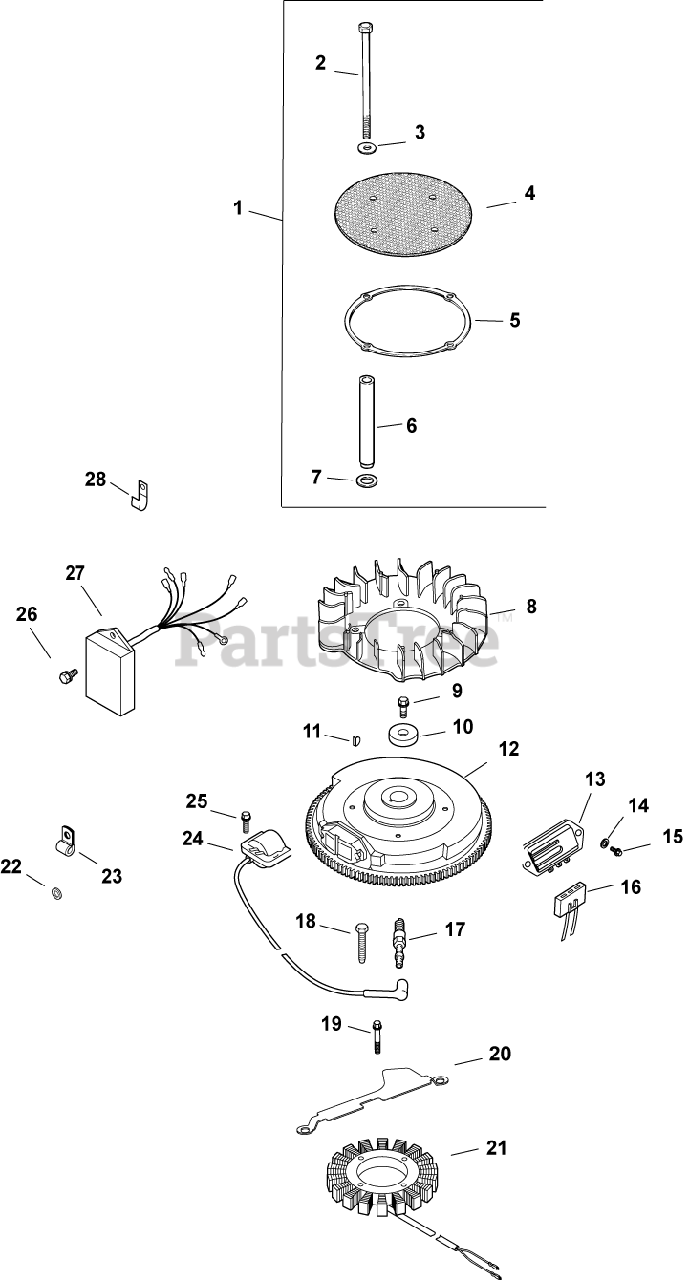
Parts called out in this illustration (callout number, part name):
1	KIT, CHOPPER SCREEN
2	SCREW, CAP M6X1.0X99.5
3	WASHER, FLAT 1/4" (O.D. 5/8")
4	SCREEN, GRASS
5	RING, SUPPORT USE 25 141 08-S
7	WASHER, SPRING 10 MM
8	FAN (DOMED)-USE 24 157 17-S
9	SCREW, FLG M10X1.5X45 - (#25086361S)
10	WASHER, FLAT 13/32"
11	KEY, 3/16" X 5/8"
12	FLYWHEEL, PAINTED-USE 24 025 56-S
13	REG/RECT-15 AMP (KM)-USE 41 403 10-S
14	WASHER, FLAT 3/16"
15	SCREW, PHL HD #11-16X7/8"
16	CONNECTOR, BODY (KM)-USE 25 155 41-S
17	PLUG, SPARK (STD)
18	SCREW, M5X0.8X25 - (#25086402S)
19	SCREW, SKT SET #10-24X1/4"
20	BRACKET, STATOR WIRE
21	KIT, 15 / 20 AMP STATOR
22	WASHER, FLAT 1/4" (O.D. 1/2")
24	MODULE, IGNITION
25	SCREW, FLG THD FRM M5X.8X20-(#25086399S)
26	SCREW, THD FRM M4X0.7X10
27	MODULE, SPEED ADVANCE
28	CLIP, CABLE
